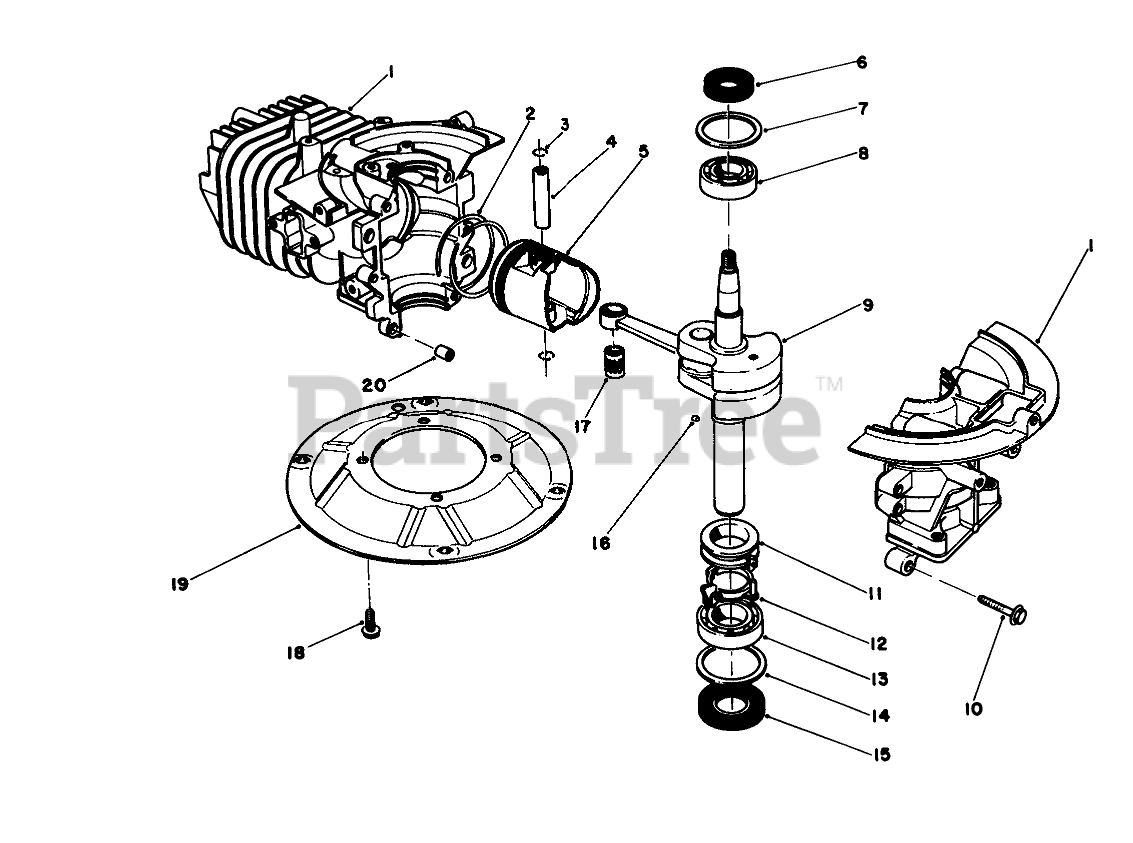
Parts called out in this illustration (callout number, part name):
1	CRANKCASE
2	RING SET
4	PIN-PISTON
5	Piston
6	OIL SEAL
7	WASHER-UPPER
8	BEARING-UPPER
9	Pin-Wrist
11	SPACER
12	BRACKET
13	LOWER BRG
14	WASHER-LOWER
15	SEAL-OIL
17	BEARING
19	PLATE-MOUNTING
